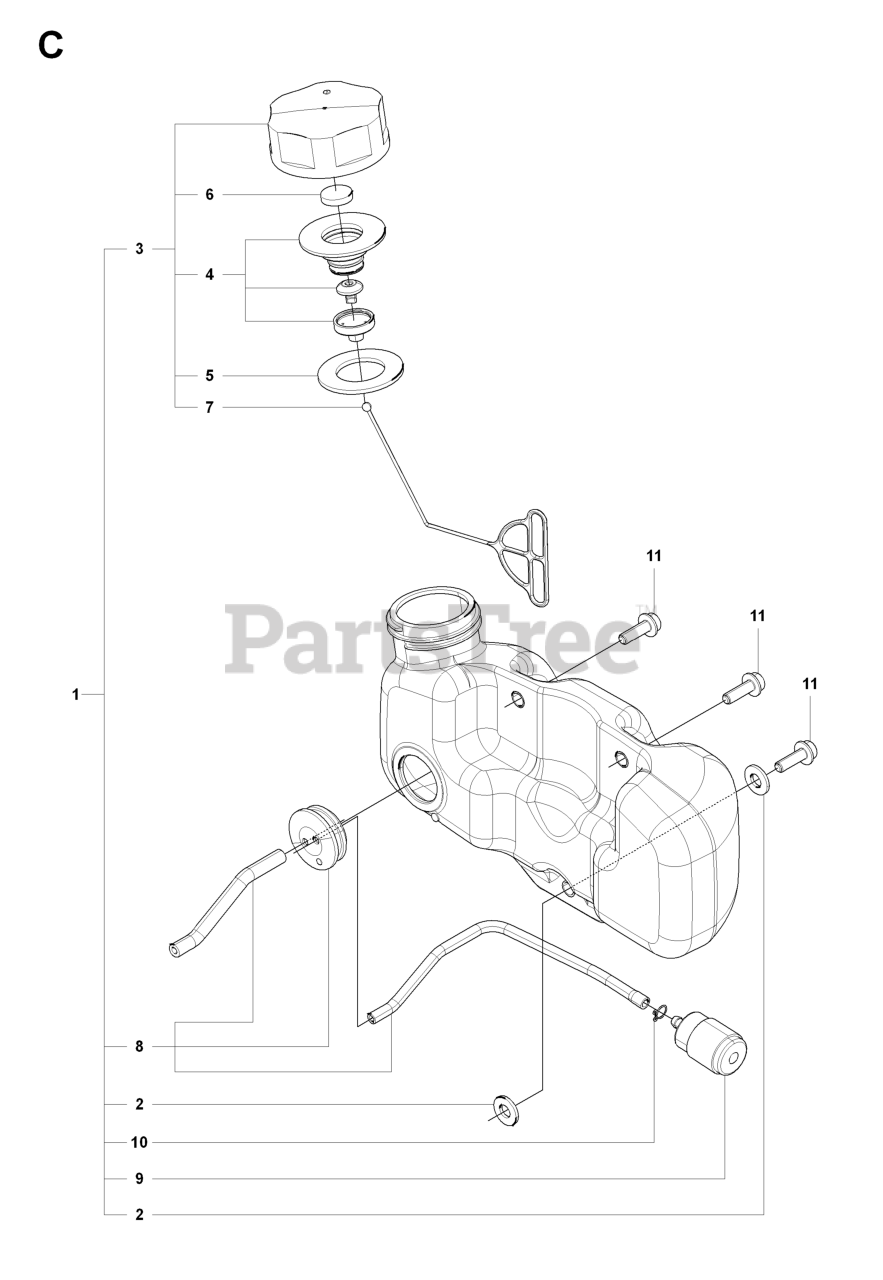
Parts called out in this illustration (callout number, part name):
1	TANK ASSY
3	CAP ASSY
4	HOLDER ASSY
5	PACKING
6	FILTER
7	STOPPER
8	PIPE COMP
9	FILTER
10	CLIP
11	BOLT TORX
